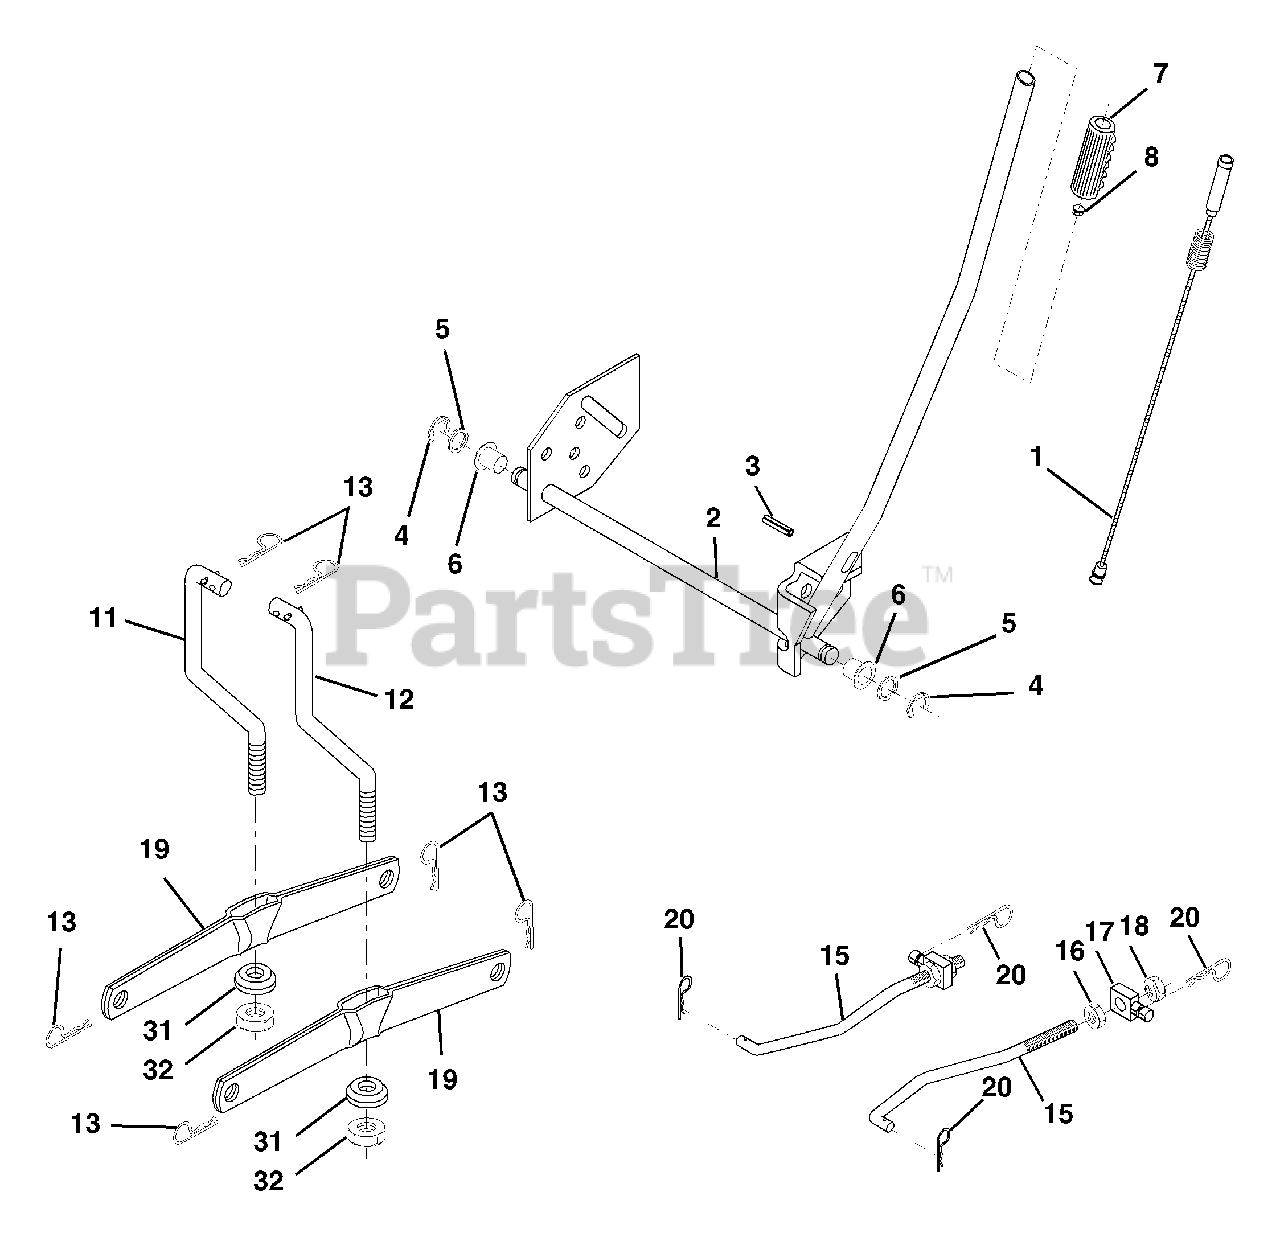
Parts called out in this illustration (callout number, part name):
1	Wire Asm Inner/Sprg w/plunger
2	Shaft Asm Lift RH
3	Pin Groove 1 500 Zinc
4	E Ring #5133-62
5	Washer 21/32 X 1 X 21 Ga
6	Bearing Nylon Blk 629 Id
7	Grip Handle Bicycle Matte Blk
8	Button Plunger Black
11	Link Lift LH Fixed Length
12	Link Lift RH Fixed Length
13	Retainer Spring
15	Link Front
16	Nut Jam Hex 1/2-13 Unc
17	Trunnion
18	Nut Lockw/Wsh 1/2-13 Unc
19	Arm Suspension Rear
20	Retainer, Spring
31	Bearing Pvt Lift
32	Nut Crownlock 3/8-24
